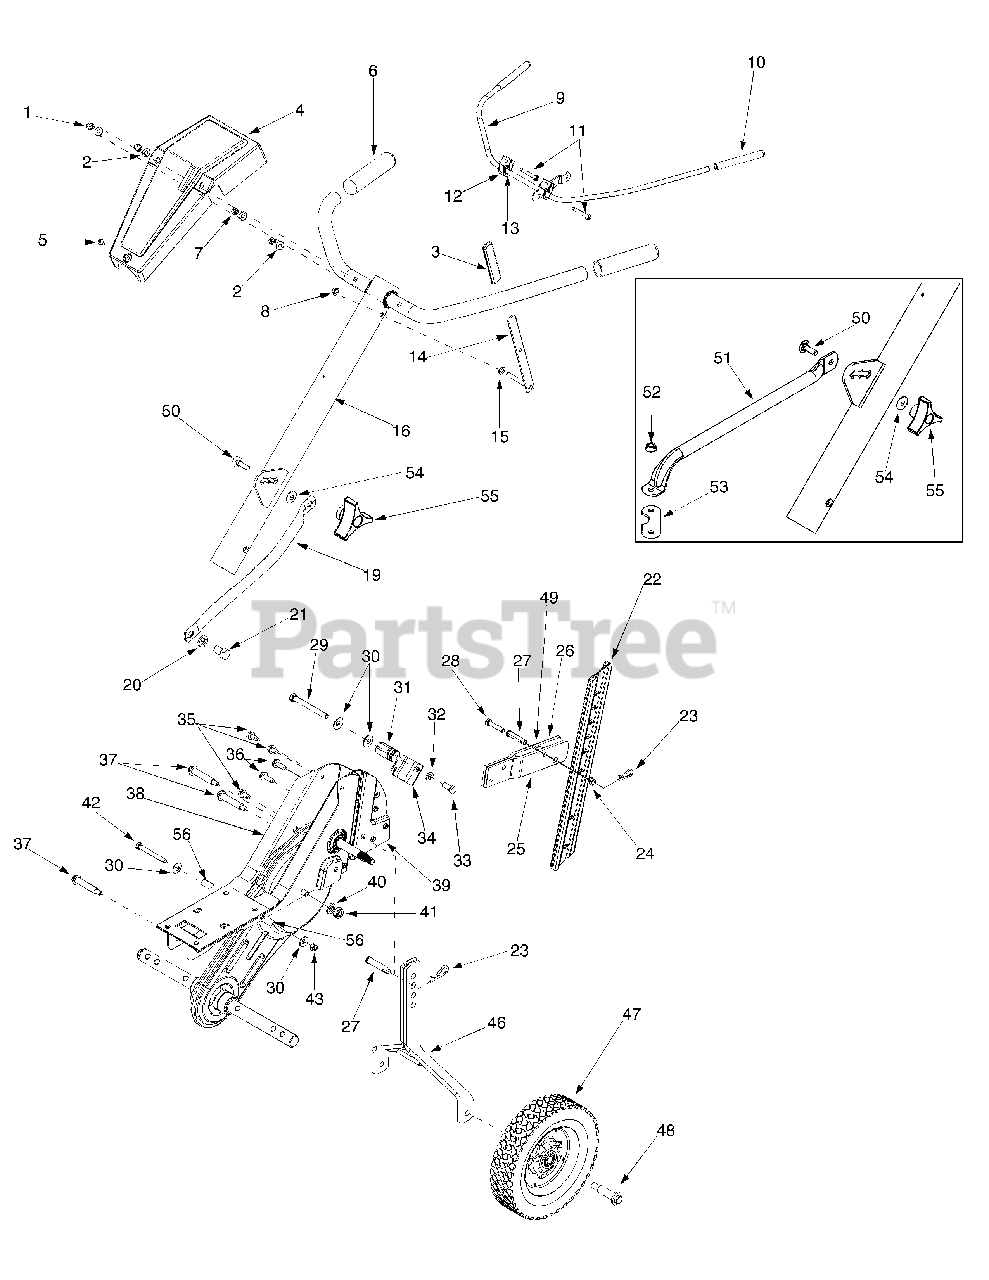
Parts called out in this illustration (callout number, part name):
1	Acorn Lock Nut 1/4-20
2	Flat Washer.271" I.D. x.630" O.D.
3	Reverse Handle Grip
4	Handle Cover w/o throttle
5	Truss Mach. Scr. #10 x 1/2" Lg.
6	Handle Grip
7	Hex Nut 1/4-20 Gr.2
8	Cap Speed Nut
10	Clutch Grip
11	Hex Bolt 1/4-20 x 2.25" Lg. Gr.5
12	Clutch Handle Holder
13	Flat Washer.385" I.D. x.62" O.D.
15	Flat Washer.344" I.D. x.62" O.D.
20	Lock Washer 1/2
21	Hex Bolt 1/2-20 Gr. 5
23	Cotter Pin
24	Hex Flange L-Nut 5/16-18 Thd. Gr.5
27	Clevis Pin
28	Hex Bolt 5/16-18 x 1.5" Lg.
29	Hex Bolt 5/16-18 x 3" Lg.
30	Wash. Bell.340" I.D. x.872" O.D.
31	Spec. Hex Nut
32	L-Wash. 5/16" I.D.
33	Hex Bolt 5/16-18 Gr. 5
35	Hex Washer Screw 5/16-18 x.62" Lg.
36	Hex Wash. Hd. TT-Tap Scr.
37	Shdl. Bolt 5/16-18
40	Lock Washer 7/16
41	Jam Nut 7/16-20 Gr. 2
42	Hex Bolt 5/16-18 x 2.75" Lg.
43	Hex Nylon Nut 5/16-18 Thd.
47	Wheel Ass’y 8" x 1.75"(Plastic)
47	Wheel Ass’y 8" x 1.75" w/Ball Bearing, (Steel)
47	Ball Bearing for steel wheel
48	Shoulder Screw.496 I.D. x 1.445 O.D.
49	Spacer
50	Carr. Bolt 5/16-18 x 1
53	Engine Brkt.
54	Bell. Wash.34" I.D.
55	Hand Knob
56	Spacer
